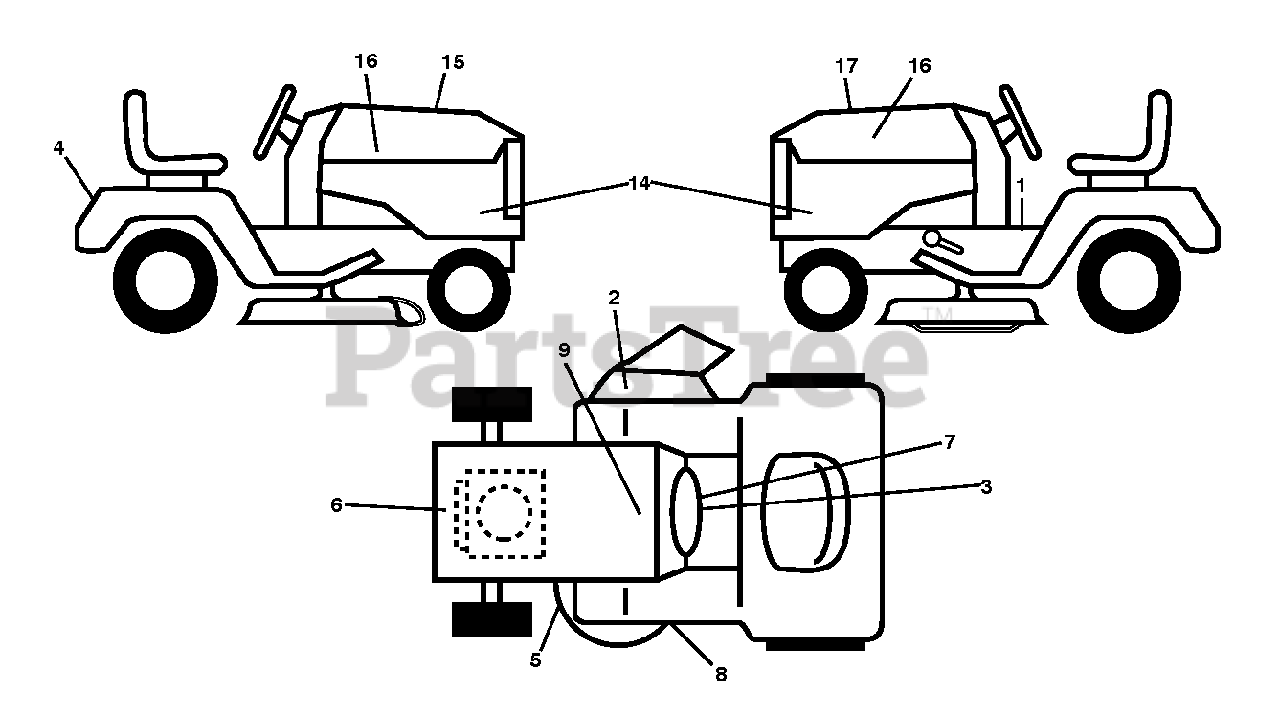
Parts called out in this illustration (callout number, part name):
1	DECAL.WARN.STARTINST.LOWEARIEN
2	DECAL.MOWER.WARN.KEEP.HAND.AWY
3	DECAL, WARNING SPARK ARRESTOR
4	DECAL.FENDER
5	DECAL.MOWER.CAUTION.TENSION.AR
6	DECAL.ENG.BS.INTK.24HP.382016
7	DECAL.SNOWFLAKE.MS498.HUSQ
8	DECAL.MOWER.SCH.48/54.PREM
9	DECAL BTRY SYMBOLS
14	DECAL SIDE PANEL
15	DECAL.WARNING.CUST.RESP.E85.
16	DECAL.BADGE.170MM.TEXTLOGO.
17	DECAL.RPL.BSM.44.INTK.TLW.48
